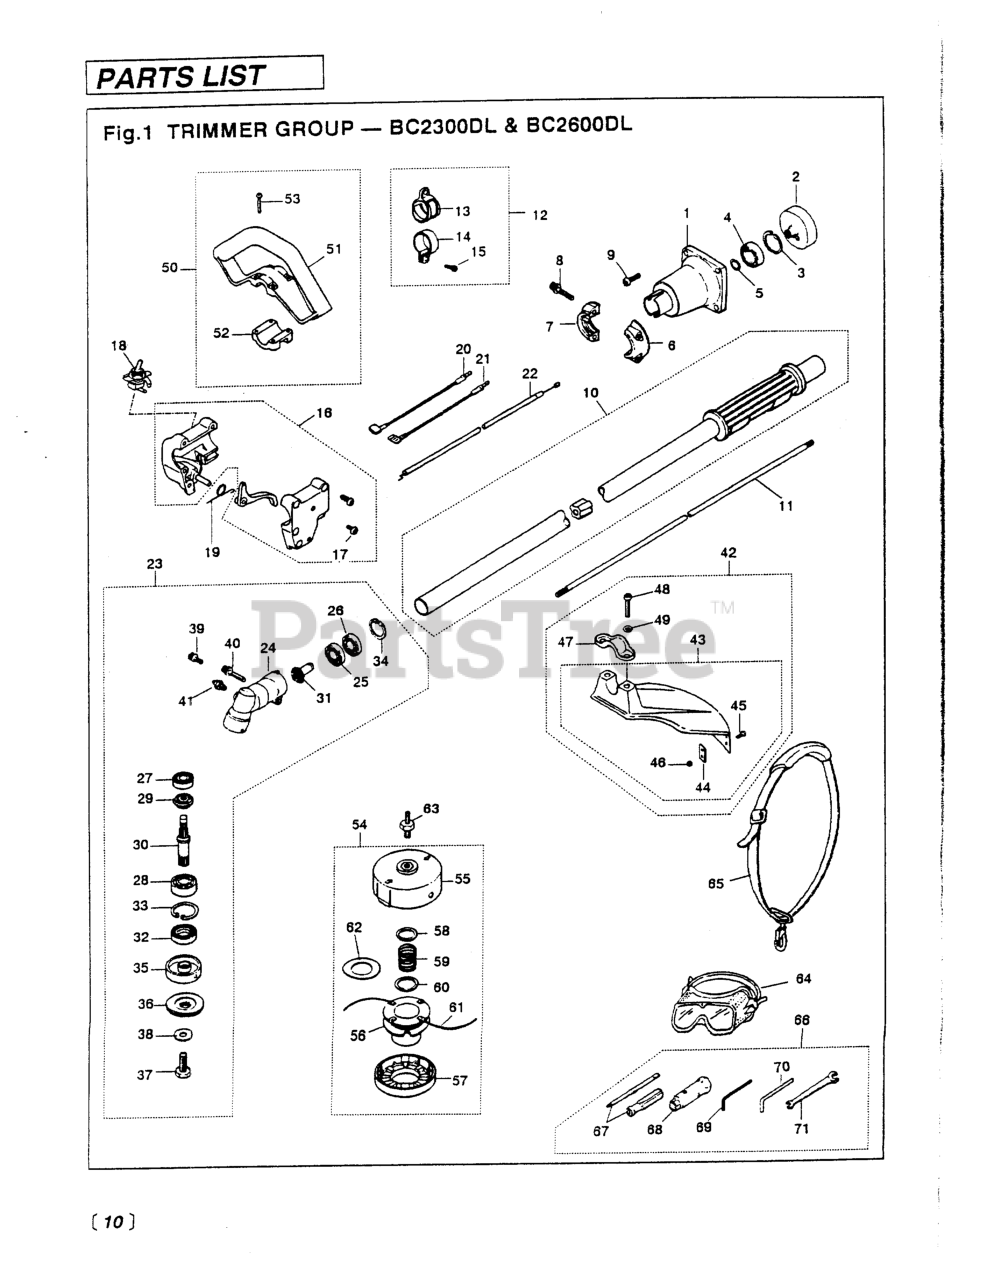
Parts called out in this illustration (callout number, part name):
3	RING, SNAP, M28 x 1.2
4	BEARING
6	CLAMP, LEFT
7	CLAMP, RIGHT
8	BOLT
9	BOLT, M6 X 20
12	HANGER COMPLETE
13	HANGER
14	CLAMP
15	SCREW, M5 x 25
17	SET SCREW, ANTI-ROTATION
18	SWITCH, STOP
19	SPRING, THROTTLE TRIGGER
20	CORD, RED (LEAD WIRE)
21	CORD, BLACK (LEAD WIRE)
23	GEARCASE ASSEMBLY
24	GEARCASE
25	BEARING
26	BEARING
27	BEARING
28	BEARING
29	GEAR
31	PINION
32	SEAL, OIL
33	RING, SNAP
34	RING, SNAP
35	HOLDER (A)
36	HOLDER (B)
38	WASHER
39	BOLT, M5 x 12
40	BOLT, M5 X 25
41	FITTING, GREASE
42	GUARD ASSEMBLY
44	BLADE
45	SCREW, M5 x 12
46	NUT
47	CLAMP
48	BOLT, M6 x 1.30
49	WASHER, M6 X 15
50	HANDLE ASSEMBLY
51	HANDLE
52	CLAMP
53	SCREW, M5 x 35
54	4
58	PLATE, LARGE
60	PLATE, SMALL
61	CORD
62	SPACER
63	ARBOR, 8MM
64	GOGGLE
65	SHOULDER STRAP ASSY
66	TOOL SET
67	SCREWDRIVER
69	WRENCH (TOOL)
70	BAR
71	SPANNER, 8 X 10 (RPLS 2540- )
